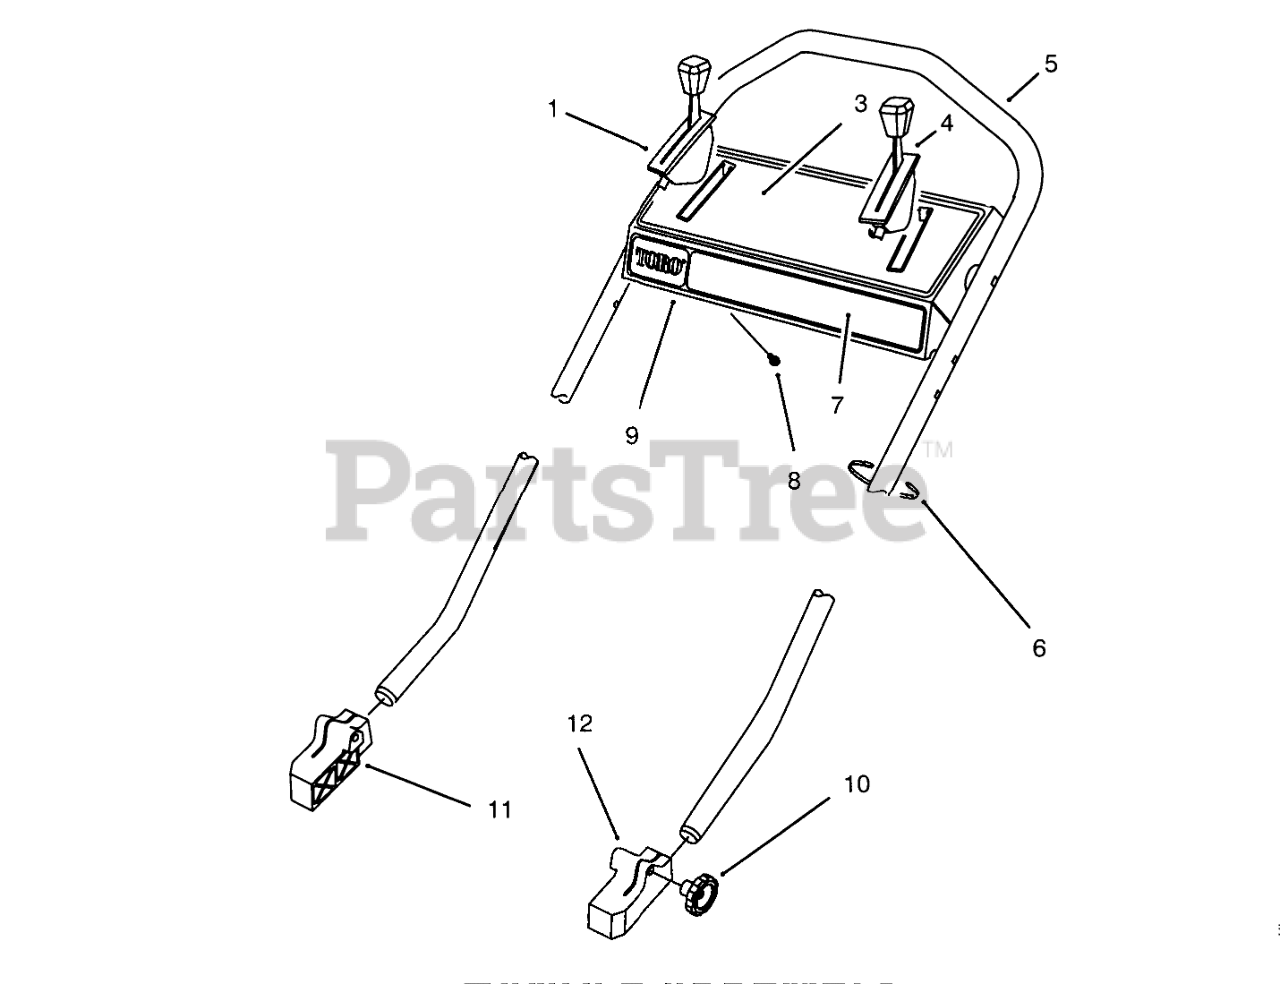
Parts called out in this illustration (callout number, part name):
1	CONTROL-SPEED, GROUND
3	DECAL - INSTRUCTION
4	SERVICE ONLY
5	HANDLE - 53CM (DIPPED)
6	TIE-CABLE
7	DECAL - PANEL BBC
8	SCREW-TAP
9	Control Panel Assembly (Incl Ref3,7)
11	MOUNT-HANDLE, RH
12	MOUNT-HANDLE, LH
